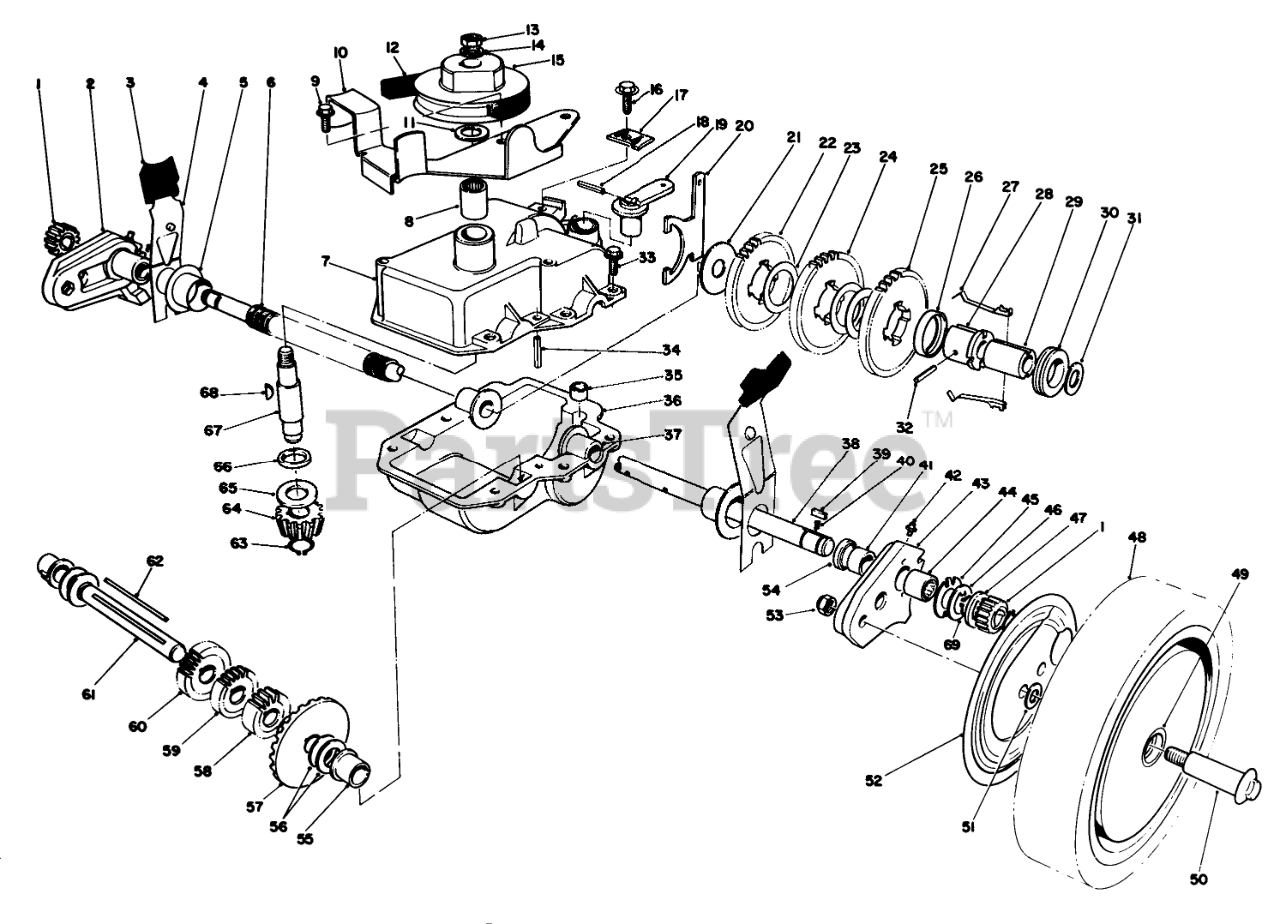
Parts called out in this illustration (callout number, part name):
1	GEAR-PINION
2	Pivot Arm Assembly-R.H. (Incl. Ref. #41, 42, 44 & 54)
3	KNOB-ARM
4	SPRING ARM ASM SP
5	CAP-END
6	CONDUIT-CONVOLUTED, SPLIT
7	Case-Upper
8	BEARING
9	SCREW
10	BELT GUIDE BRKTB
11	WASHER-THRUST
12	V-BELT
13	NUT-HEX
14	WASHER-FLAT
15	PULLEY
16	SCREW-HWHTF
17	Cable Clamp
18	PIN-COIL
19	LEVER-SHIFT
20	Shift Yoke
21	WASHER
22	GEAR-38T
23	WASHER
24	GEAR-42T
26	RETAINER-KEY
27	KEY-SHIFT
28	SLEEVE-GEAR
29	SLEEVE
30	COLLAR-SHIFT
31	WASHER-PLAIN
32	PIN-SPRING
33	SCREW-HWHTF
34	ROLL PIN 3/16 X 1 IN
35	BUSHING-YOKE
36	LOWER GEAR CASE CAST
37	Bushing-Output Shaft
38	Output Shaft
39	KEY RECTANGULAR
40	SPRING-COMPRESSION
41	BUSHING
42	FITTING-GREASE
43	Pivot Arm Assembly-L.H.(Incl. Ref. #41, 42, 44 & 54)
44	BEARING-ROLLER
45	INNER THRUST WASHER
46	WASHER-THRUST, OUTER
47	WASHER-THRUST, OUTER
48	Wheel, Tire & Gear Assembly (Incl. Ref. #49)
49	BUSHING
50	BOLT-WHEEL
51	WASHER
52	WHEEL COVER
53	Nut
54	SEAL-OIL
55	BUSHING
56	WASHER-THRUST
57	BEVEL GEAR
58	GEAR-12T
59	GEAR-14T
60	GEAR-18T
61	INTERMEDIATE SHAFT
63	RING-RETAINING
64	PINION-BEVEL
65	WASHER-THRUST
67	INPUT SHAFT
68	KEY-WOODRUFF
69	RING-RETAINING
